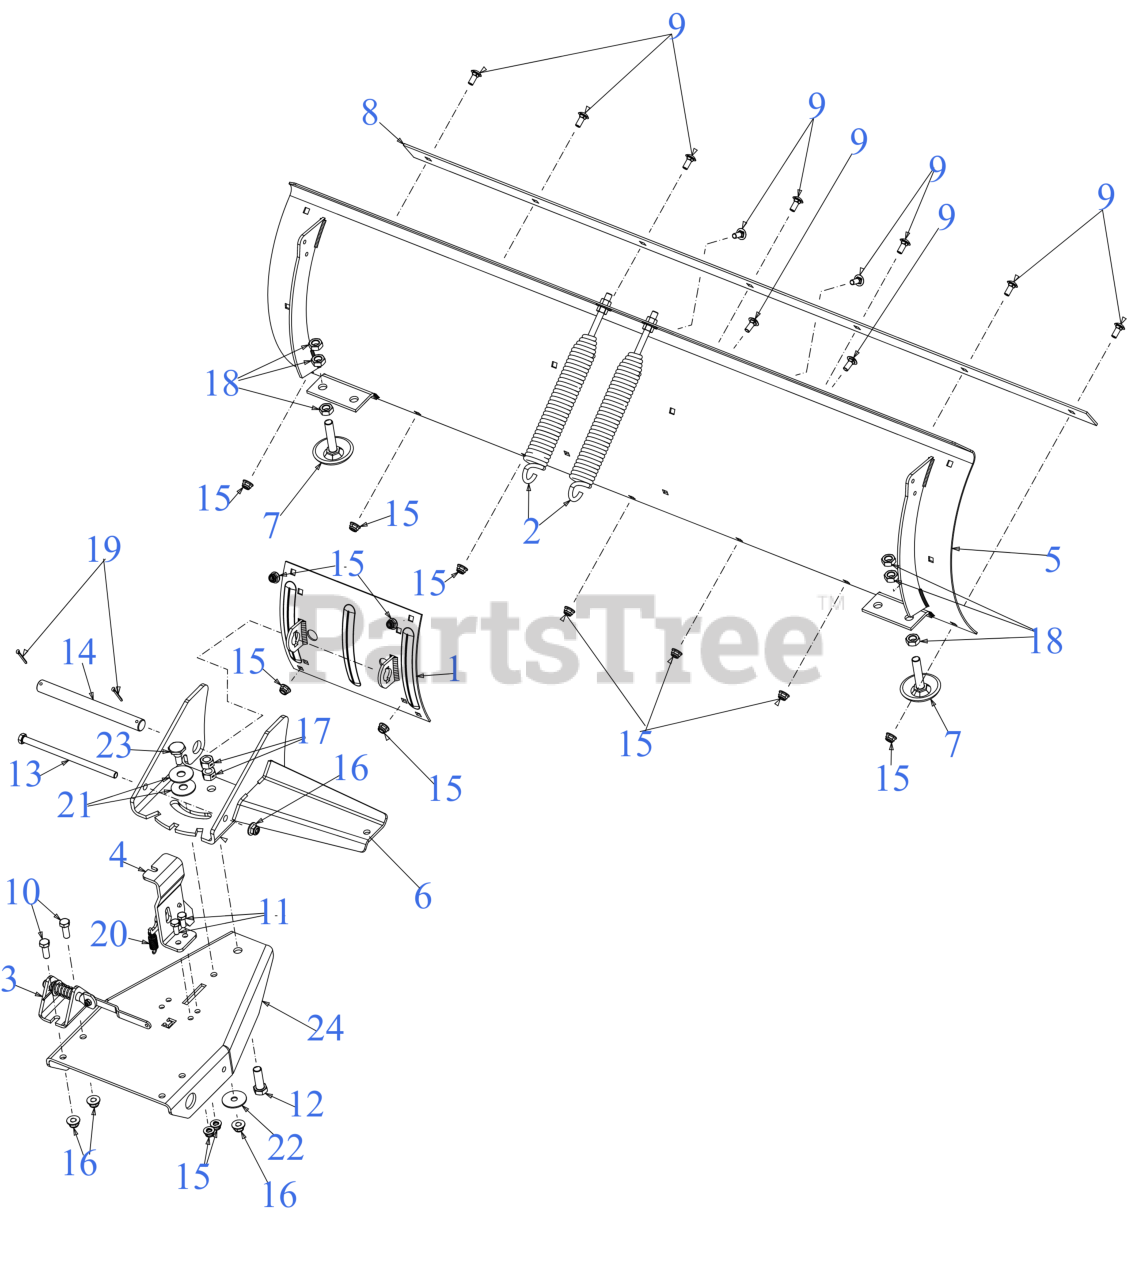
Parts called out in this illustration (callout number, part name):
1	REINFORCEMENT PLATE
2	TRIP SPRING KIT
3	LOCKING ASSEMBLY
4	LOCK LEVER ASSEMBLY
5	52" BLADE
6	PIVOT PLATE
9	CARRIAGE BOLT 5/16-18 x .75
10	SCREW 3/8-16 x 1 GR5
11	SCREW 5/16-18 x .75 GR5
12	SCREW 1/2-13X1.50 GR5
13	SCREW 3/8-16 x 7.00 GR5
14	PIVOT SHAFT
15	FLANGE LOCK NUT 5/16-18
17	HEX NUT CTR LK 1/2-13
19	COTTER PIN
20	EXTENSION SPRING
21	WASHER .51 x 1.5 x .07
22	FLAT WASHER .390 ID x 1.50 OD x .075
23	SHOULDER SCREW
